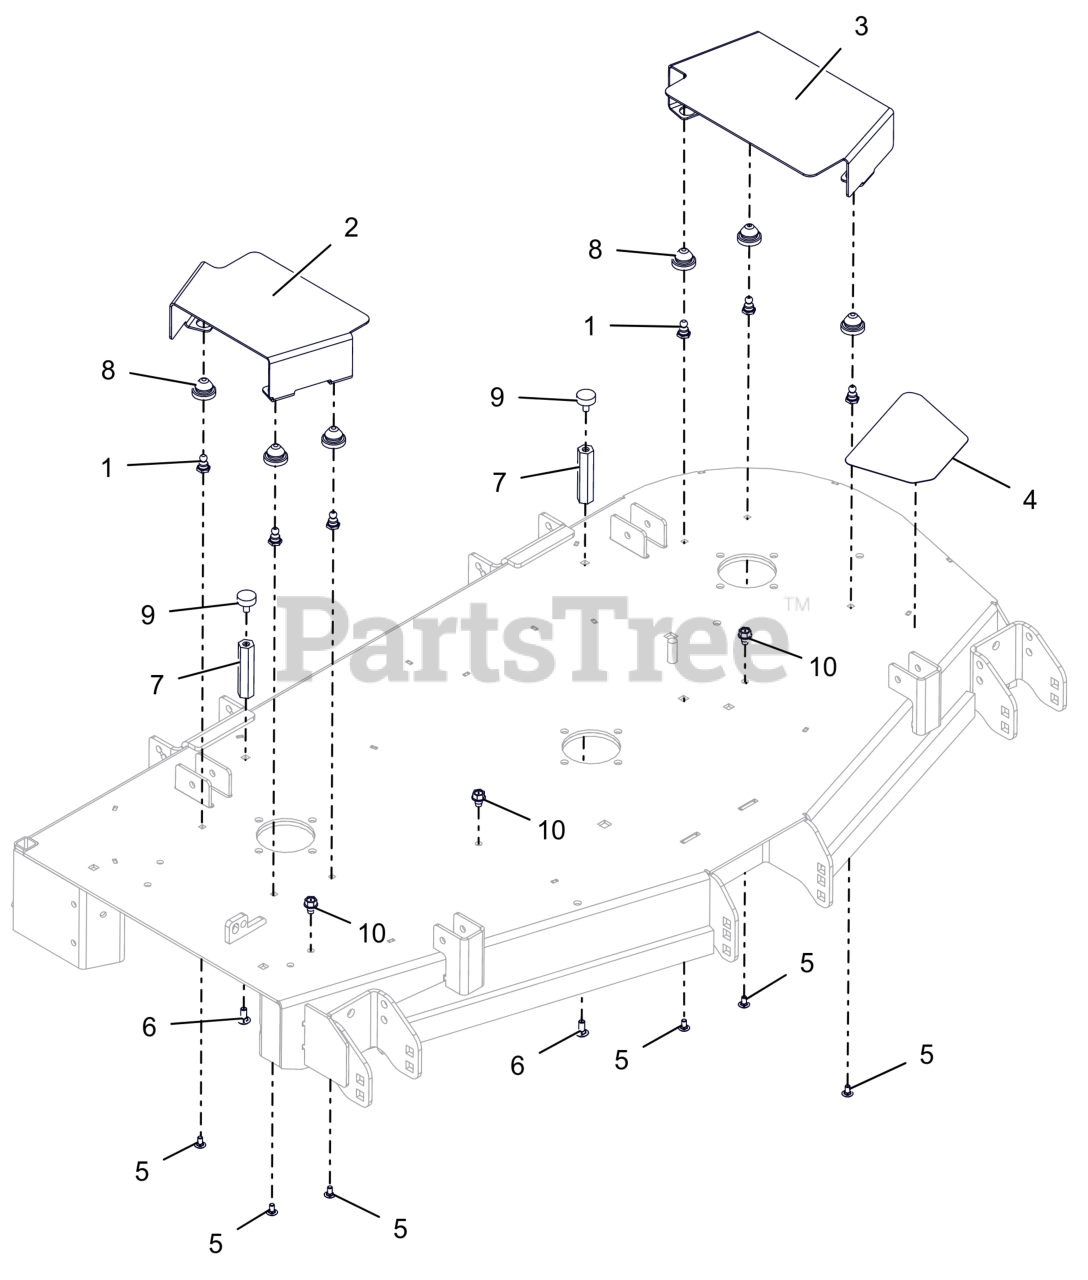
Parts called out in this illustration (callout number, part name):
1	STUD, BALL FEMALE .250-20 THREAD
2	GUARD, RH DECK BELT (RED)
3	GUARD, LH DECK BELT (RED)
4	GRIP, STEP ANTI SKID
5	BLT, RHSSN.25-20X.500 G5 ZCC
6	BTL,RHSN .313-18 X 0.75 G5 ZCC LT
7	NUT, COUPLING .312-18 X 3.250
8	COUPLING, RUBBER PUSH-IN
9	BUMPER, RUBBER
10	SCR,TAP .375-16X.50 HWH TR ZCC
